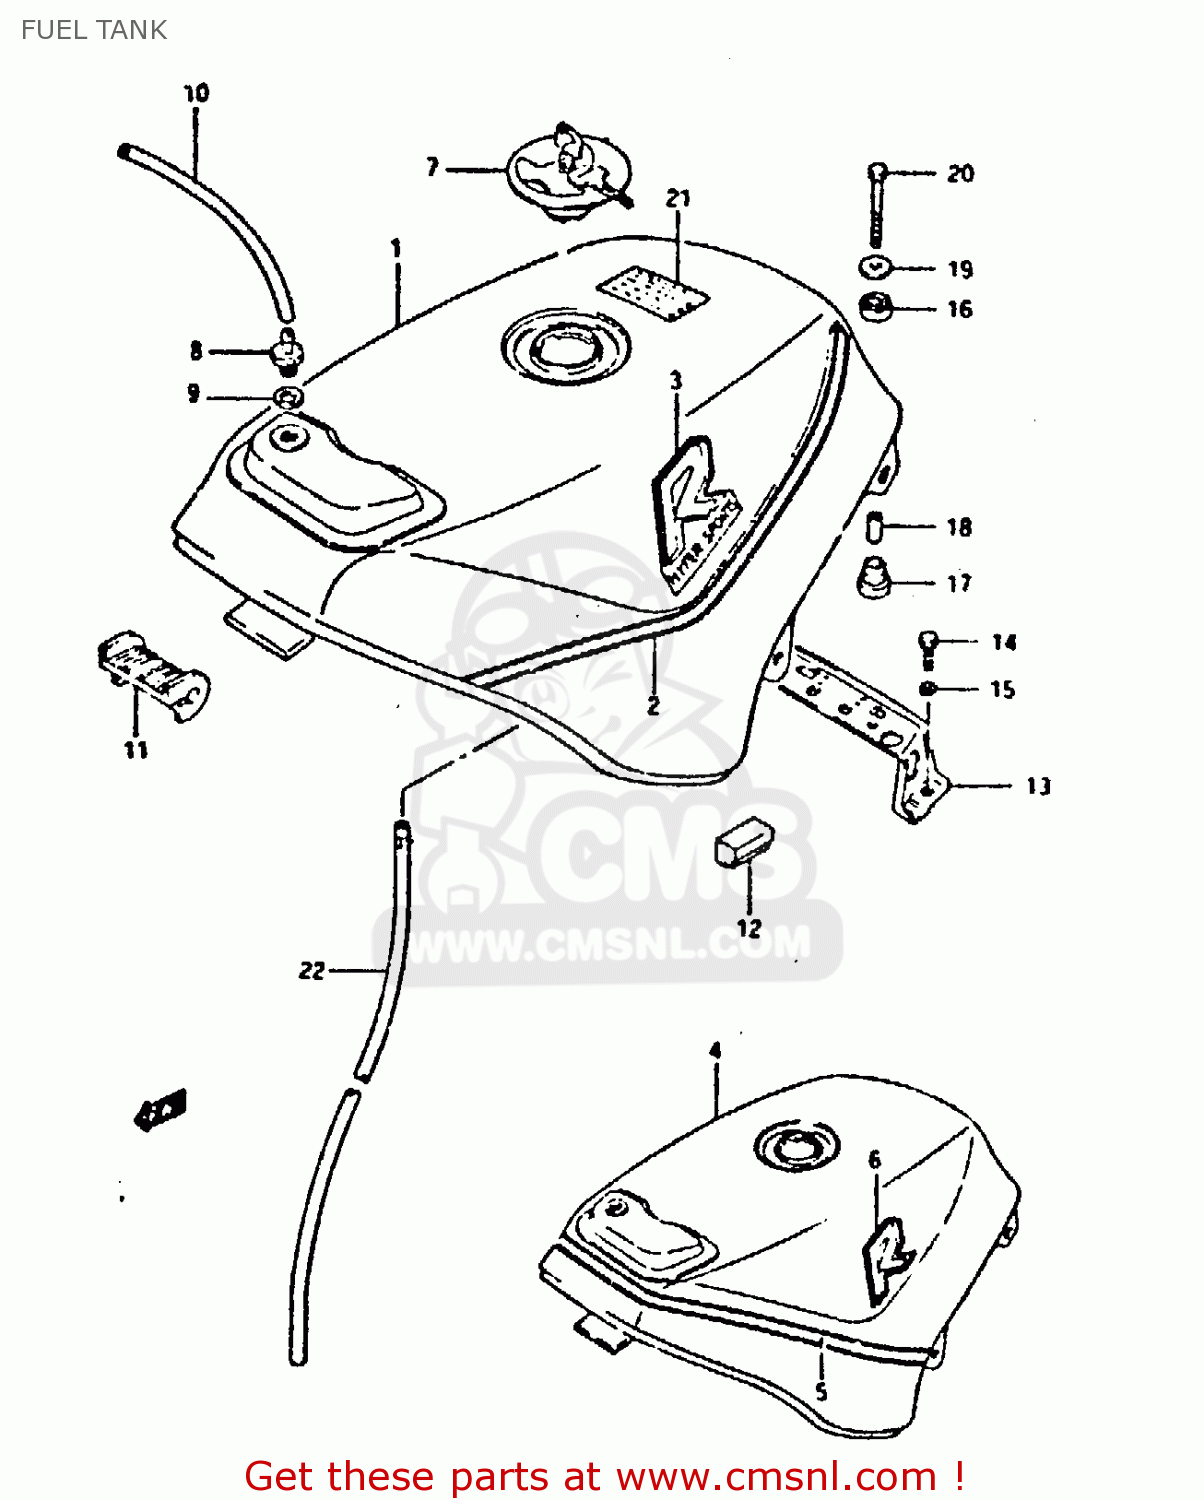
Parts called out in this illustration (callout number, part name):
3	EMBLEM,FUEL TANK
4	BENZINE TANK
7	CAP SET,FUEL TANK
8	PLUG,FUEL TANK BREATHER
9	GASKET(12.5X20X2.5) (NAS)
10	HOSE
11	CUSHION.FUEL TA
12	CUSHION,FUEL TANK SIDE
14	SCREW
15	WASHER,LOCK
16	CUSHION
17	CUSHION
18	SPACER (6.4X9X20)
19	WASHER (6.5X24X1.6)
20	BOLT ,6X35
21	LABEL
22	HOSE,FUEL
